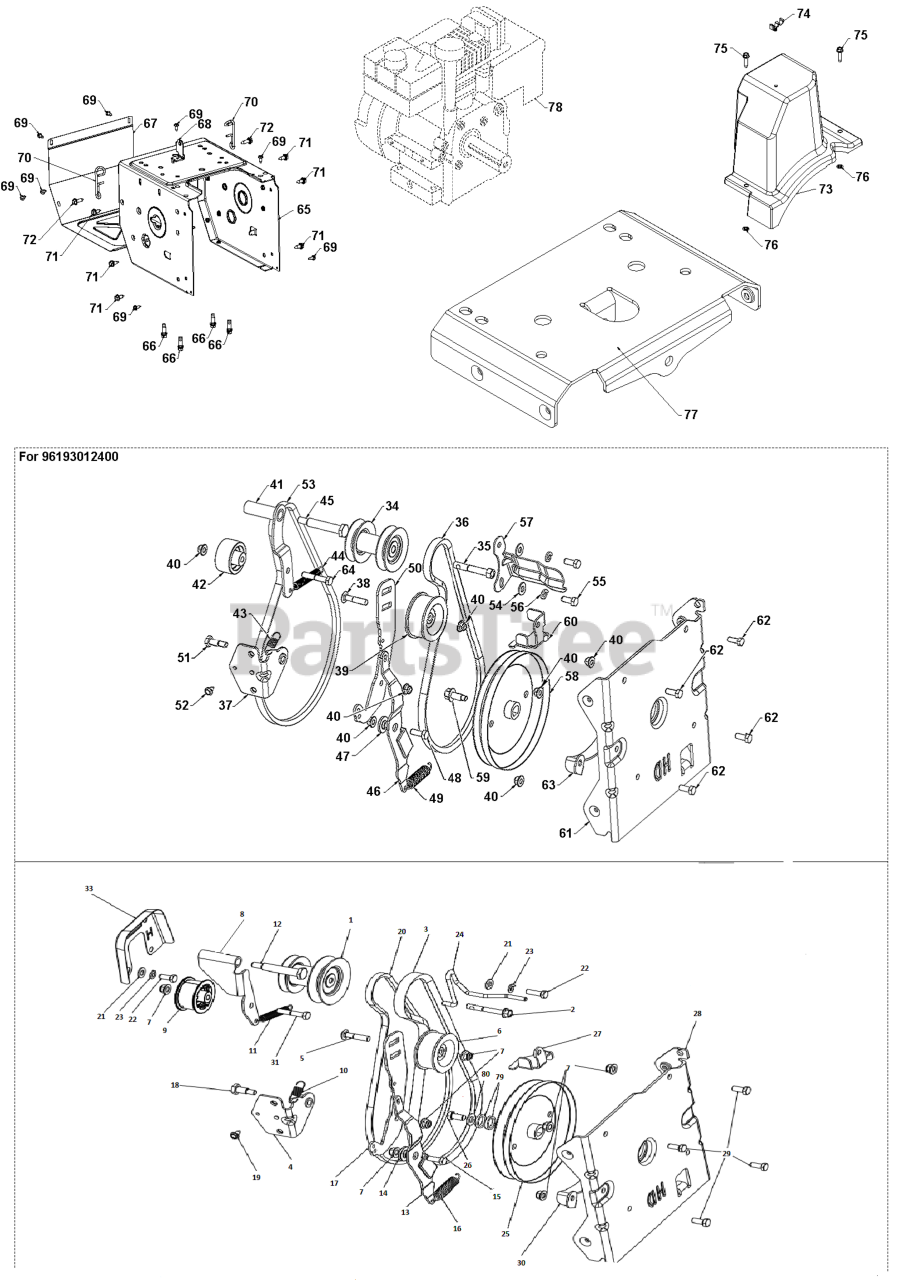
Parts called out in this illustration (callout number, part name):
1	PULLEY 5L GEAR
3	BELT 5L 39.15L
4	BRACKET WELDMENT, IDLER ARM ZI
5	BOLT 5/16-18 CARRIAGE 1.5L
7	NUT HEXAGON FLANGE 5/16-18 ST
7	NUTNYLOK.FLRANGE.5/16-18
8	ARM DRIVE IDLER CLEAR ZINC PLA
9	PULLEYIDLER.2.0.W/SPACER.CZ
10	SPRING IDLER RETURN
11	SPRING RETURN IDLER ARM
12	BOLT 5/16-24X2.25 HEX HEAD SHO
13	ARM IMPELLER BRAKE
14	BUSHING.BRAKE.ARM
15	BOLT HEXAGON BOLT 5/16-18 X 7/
16	SPRING EXTENSION - BRAKE
17	ARM IDLER BLACK ZINC
18	SCREW HEX HEAD SHOULDER
20	BELT 3L 39.68; POLY CORD
21	WASHER M
21	WASHER 11/32 X 11/16 X 14 GA T
22	SCREW 5/16-24 X .75 GR5
23	WASHER SPRING LOCK WASHER WITH
24	GUIDE BELT - 3L FRICTION, 5L I
24	GUIDE.BELT.5L.IMPELLER.3L.DRV
25	PULLEY IMPELLER DD 5L HD
26	SCREW FLANGE HEAD CAP WITH DOG
26	SCREW HEXAGON HEAD FLANGE 3/8-
28	BRACKET AUGER HOUSING INTERFAC
29	BOLT.FIN.HEX.5/16-18X3/4
29	SCREW HEXAGON HEAD SCREW 5/16-
30	BRACKET.BELT.KEEPER.LOWER.BLAC
31	BOLT, HEX 5/16-18X1-3/4
32	SCREW
33	Gutter
34	PULLEY WELDMENT
35	BOLT.ENGINE.PULLEY
36	BELT 5L 39.15L
37	BRACKET WELDMENT, IDLER ARM ZI
38	BOLT 5/16-18 CARRIAGE 1.5L
39	PULLEY IDLER
40	NUTNYLOK.FLRANGE.5/16-18
41	ARM IDLER DRIVE WELDMENT_HOT
42	PULLEY.IDLER.FLANG.2.O/SPACER
43	SPRING IDLER RETURN
44	SPRING RETURN IDLER ARM
45	BOLT 5/16-24X2.25 HEX HEAD SHO
46	ARM IMPELLER BRAKE
47	BUSHING.BRAKE.ARM
48	BOLT
49	SPRING EXTENSION - BRAKE
50	ARM IDLER BLACK ZINC
51	SCREW HEX HEAD SHOULDER
53	BELT 3L 39.68; POLY CORD
54	WASHER M
55	SCREW 5/16-24 X .75 GR5
56	WASHER.LOCK.HVY.HLCL.SPR.5/16
57	GUIDE BELT - 3L FRICTION, 5L I
58	PULLEY IMPELLER DD 5L HD
59	SCREW FLANGE HEAD CAP WITH DOG
61	BRACKET AUGER HOUSING INTERFAC
62	BOLT.FIN.HEX.5/16-18X3/4
63	BRACKET.BELT.KEEPER.LOWER.BLAC
64	BOLT, HEX 5/16-18X1-3/4
65	FRAME MS 668
66	BOLT 3/8-16X1-1/8
67	COVER COVER.FRAME MS668 ORANGE
68	BRACKET.SHIFTER.BZP
69	SCREW.HEX HEAD W/COLLAR 1/4-20
70	WIREFORM.SUPPORT.CABLE
71	BOLT.HEX.HD.WASHER.5/16-18X.75
72	SCREW HEX_SERR_HD_5_16-18X1.0
73	COVER BELT ASM HIGH CRANK
77	BRACKET.FRAME.SUP.LARGEENG.BLA
78	ENGINE.LCT.291CC.ST FORCE.SNO
78	ENGINE RATO 301CC (CARB)
78	Engines
78	ENGINE.LCT.291CC.SNO.16
78	ENGINES
78	ENGINE.LCT.369CC.SNO.16
79	WASHER.SPACER.MANDREL
80	WASHER PLAIN WASHER 3/8 X 0.08
